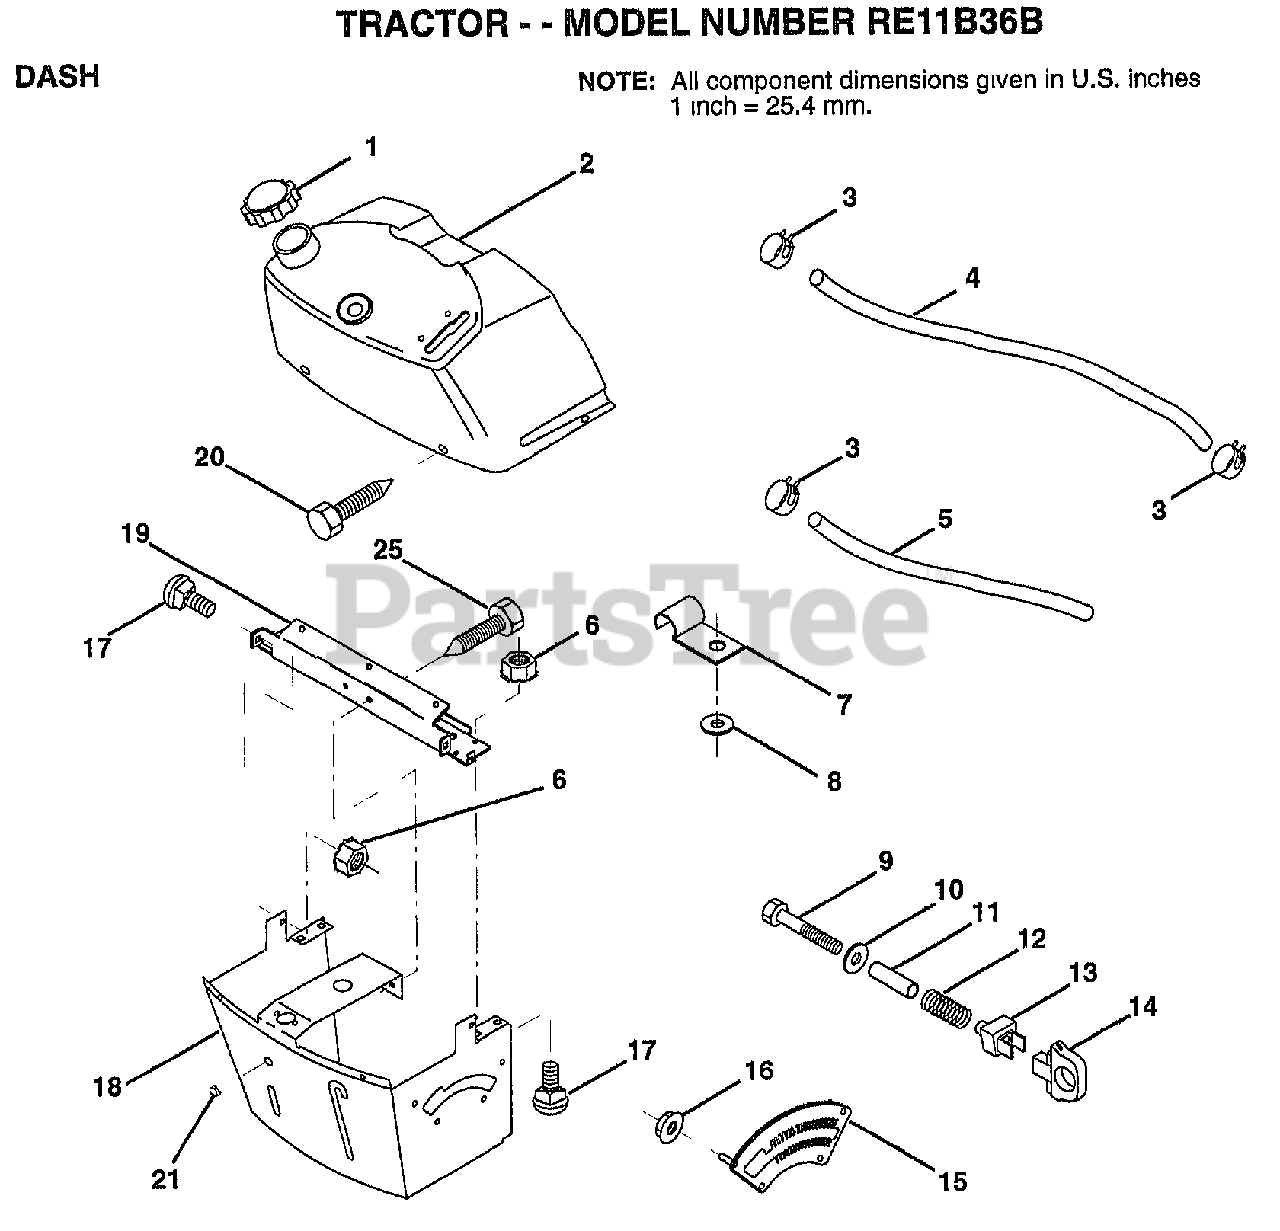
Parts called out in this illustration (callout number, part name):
1	CAP BLK FUEL LR
2	TANK.ASM.DASH.LR
3	HOSE CLAMP
5	FUEL LINE T
6	NUT HXKEP 1/4X20
7	CLIP T
8	WASHER PM
9	BOLT
11	SPACER SPLIT
12	SPRING M
13	"KNOB,HGT RETAINER"
14	KNOB
15	ADJUSTER QUAD
16	NUT
17	BOLT
18	SUPT ASSY DASH
19	CROSS BRACE
20	SCREW.1/4-20X1/2
21	PLUG DOME
25	SCREW LT
